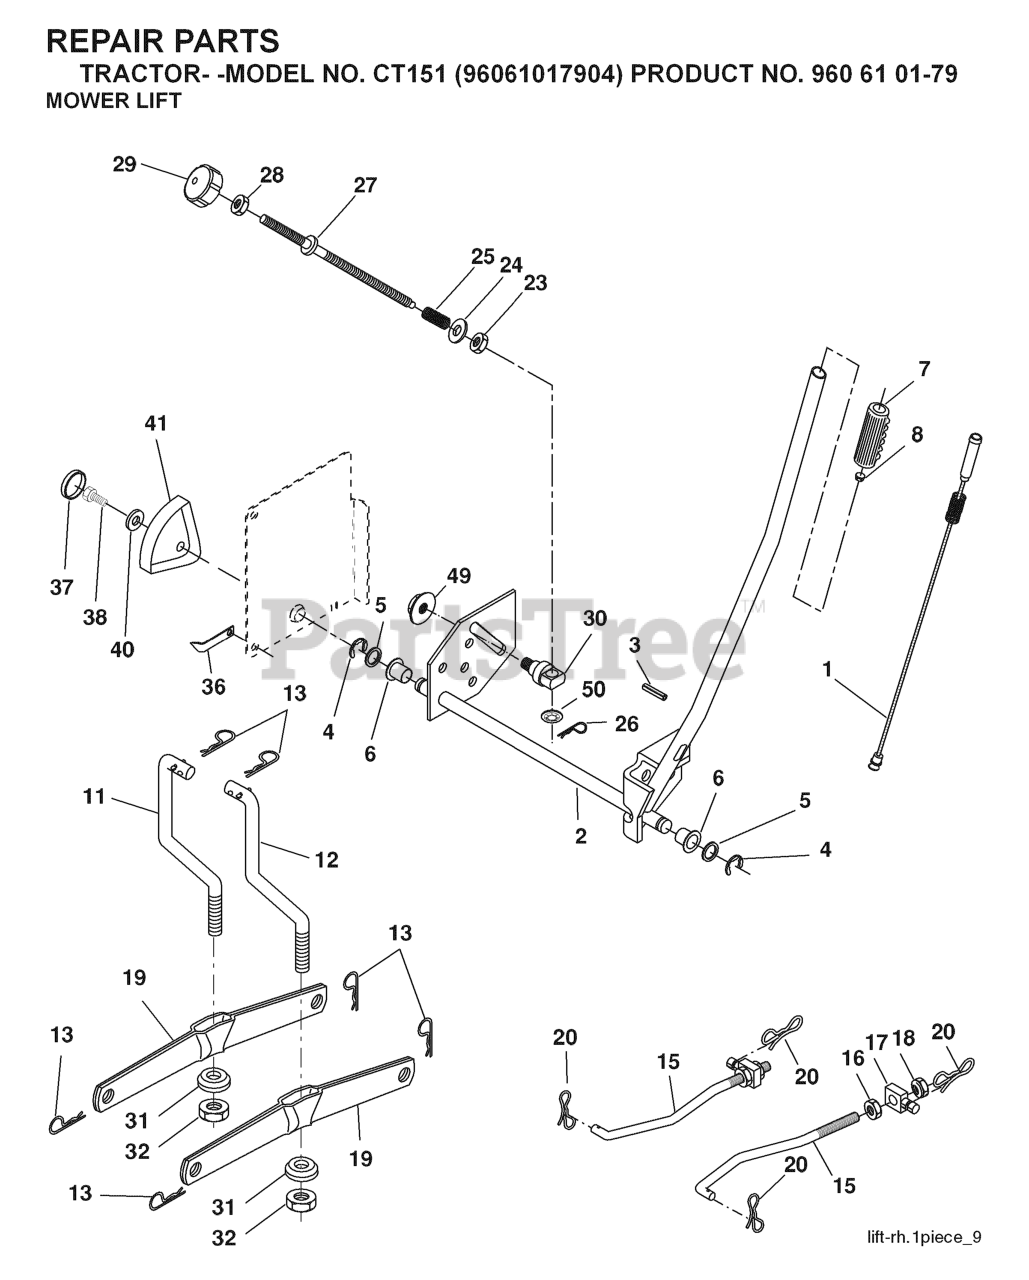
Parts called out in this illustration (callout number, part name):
1	WIRE ASM INNER W/ PLUNGER LT
2	SHAFT ASM R HANDLE
3	PIN GROOVE.
4	RETAINING RING LT
6	BEARING.NYLON
7	GRIP HANDLE
8	REPL BY 532 12 59-25
11	LINK
12	LINK
13	RETAINER-SPRNG RB
15	LINK.SUSPENSION.FRONT
16	NUT.HEX.JAM.1/2-13
18	NUT.LK.W/WSH.1/2.
19	ARM.REAR.SUSPENSION
20	PIN.COTTER.7/16.BOW TI.
26	RETAINER CLIP
27	ROD ADJ LIFT
28	NUT
29	KNOB INF 3/8-16
31	BEARING.PIVOT.LIFT
32	NUT CROWNLOCK 3/8-24
36	POINTER, HEIGHT INDICATOR(2 2)
38	SCREW 5/16-18X1
41	HEIGHT INDICATOR
49	NUT
50	NUT PUSH M
